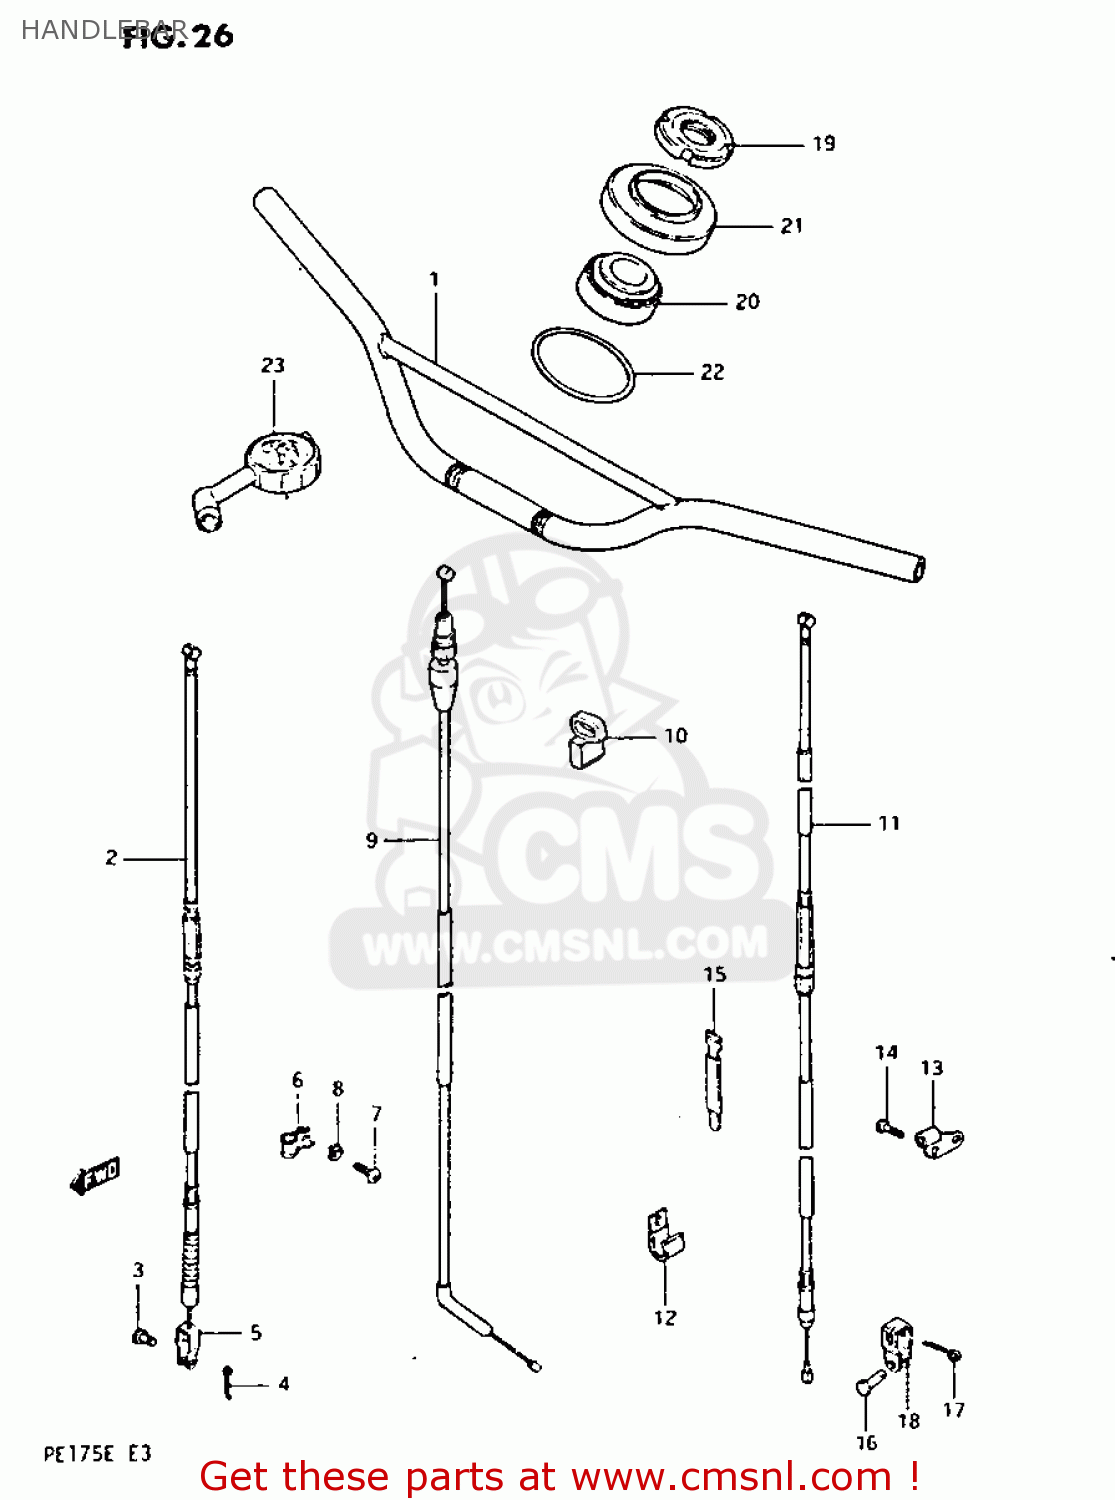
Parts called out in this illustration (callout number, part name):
1	HANDLEBAR
2	CABLE,FR BRAKE
3	PIN(L:13.5)
4	PIN
5	BRAKE CABLE HOOK
6	GUIDE,CABLE
7	SCREW
8	WASHER,LOCK
9	CABLE ASSY,THROTTLE
10	GUIDE,CLUTCH CABLE
11	CABLE,CLUTCH
12	CLAMP
13	STOPPER,CLUTCH CABLE
14	SCREW
15	CLAMP
16	PIN(L:13)
17	PIN
18	HOOK,CLUTCH CABLE
19	NUT,STEERING STEM(25X44X10)
20	TAPER,ROLLER BEARING
21	DUST SEAL,STEERING UPR
22	O RING(D:3.53,ID:69.44)
23	GAUGE ASSY,AIR PRESSURE
